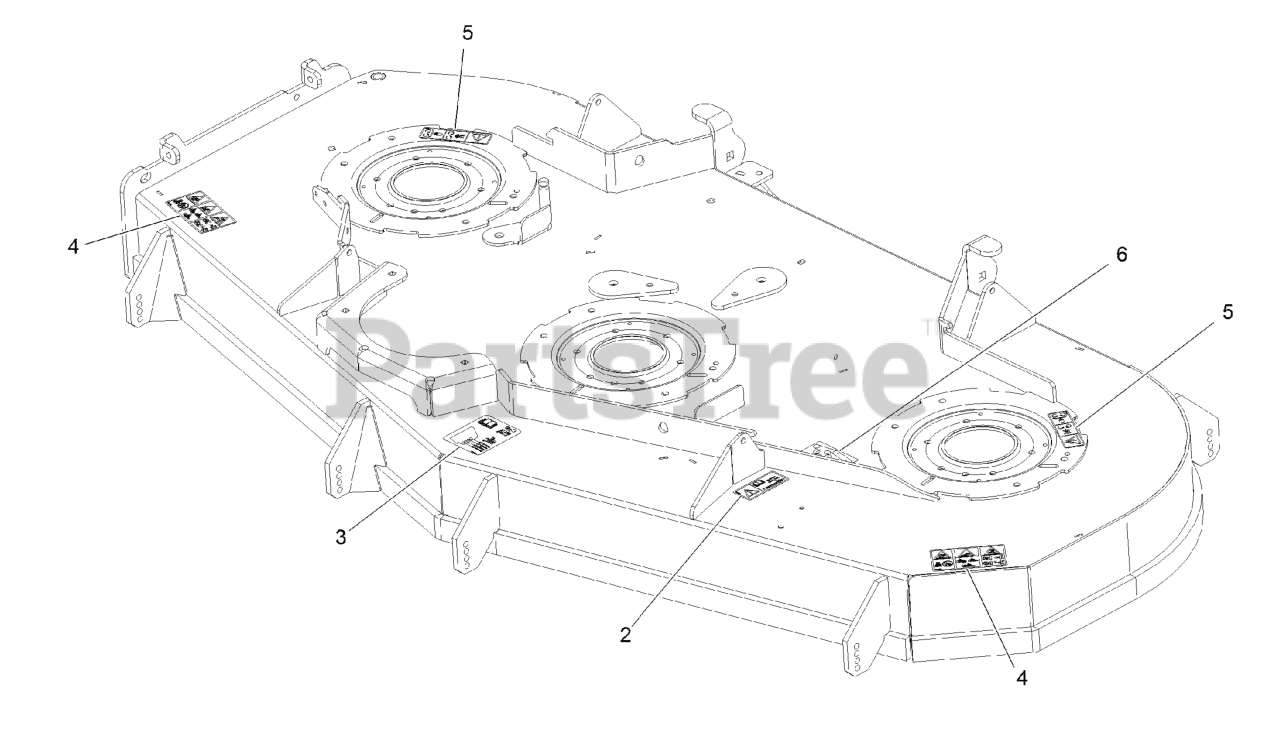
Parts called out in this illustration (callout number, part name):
2	DECAL-BOLT TORQUE
3	DECAL-ROLLER, ANTI-SCALP
4	DECAL-DANGER THROWN OBJECTS
5	DECAL-COVER, MISSING
6	DECAL-BELT ROUTING
